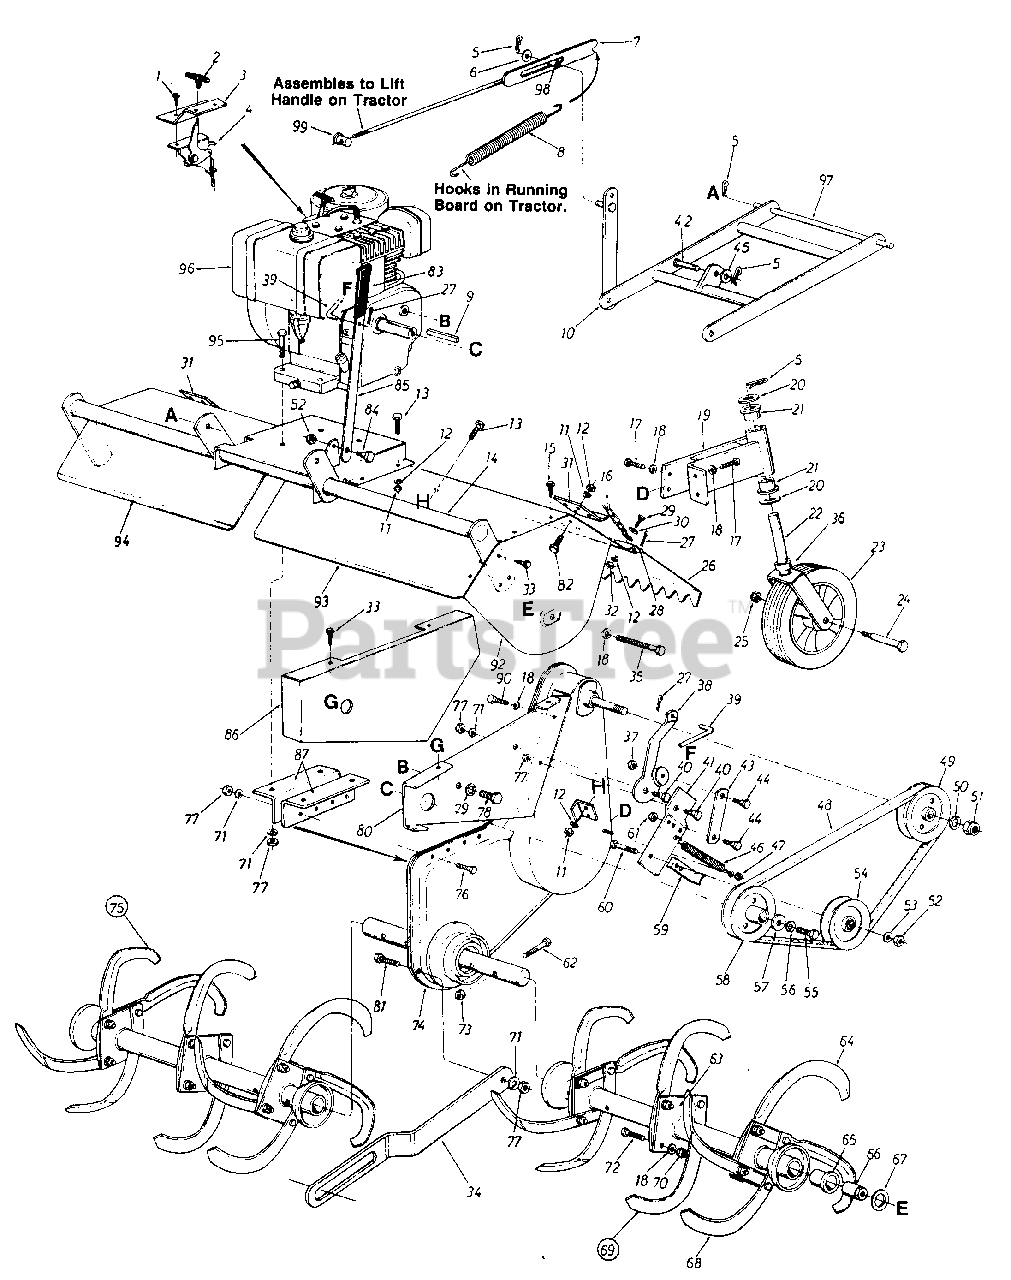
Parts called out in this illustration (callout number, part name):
1	Hex Wash. Hd. Self-Tap Scr. #8 x .50" Lg.
2	Throttle Control Knob
3	Throttle Control Bracket
4	Throttle Control Ass'y. Comp.
5	Internal Cotter Pin
6	Fl-Wash. 1/2" I.D. x .93" O.D.
9	Sq. Key 1/4" x 1/4" x 2.00" Lg.
12	L-Wash 1/4 " I . D
13	Hex Bolt 1/4-28 X .62" Lg.
16	#2 Dog Chain x 20" Lg.
17	Hex Wash. Hd. Self-Tap Scr. 3/8-24 x .75" Lg.
18	L-Wash. 3/8" I.D.
21	Flange Bearing 3/4" I.D. x 1.00" O.D.
24	Shoulder Bolt .623" I.D. x 3.62" Lg.
25	Hex Cent. L-Nut 7/16-14 Thd.
28	L.H. Flap Rod
29	Hex Bolt 1/4-20 x .6Z" Lg.
30	Fl-Wash. 1/4" I.D.
33	Hex Wash. Hd. Self-Tap Scr. 1/4" x.62" Lg.
36	Spacer .752" I.D. x 1.25" O.D.
37	Hex Cent. L-Nut 5/16-18 Thd.
40	Shoulder Bolt 7/16" Dia. x 1.75" Lg.
45	Fl-Wash. .50" I.D. x 1.0" O.D. x .06
46	Extension Spring .62" O.D. x 6.12" Lg.
47	Hex Crown Nut 3/8-24 Thd.
48	"V"-Belt '/2" x 43" Lg. (Kevlar)
49	1/2" "V"-Pulley 4.75" O.D. x .625" Bore
50	L-Wash. 5/8" I.D.
51	Hex Ins. L-Nut 5/8-18 Thd.
52	Hex Cent. L-Nut 3/8-16 Thd.
53	Fl-Wash. 3/8" I.D.
54	Idler Pulley 4.0" O.D.
55	Hex Bolt
56	L-Wash. 7/16" I.D.
57	Fl-Wash. 7/16" I.D. x 1.38"
58	'/2" "V'-Pulley .475" O.D. x 1.00" Bore
61	Hex Cent. L-Nut 5/16-18 Thd.
62	Hex Bolt 7/16-14 x 2.00" Lg.
66	Spacer
67	Thrust Wash. '/2" I.D. x 1.55"
71	L-Wash. 5/16" I.D.
72	Hex Bolt 3/8-24 x 1.5" Lg.
73	Hex Cent. L-Nut 7/16-14 Thd.
77	Hex Nut 5/16-18 Thd.
78	Hex Bolt '/2-20 x .88" Lg. (Grade 5)
79	L-Wash. '/2" I.D.
80	Clutch Support Bracket
81	Shld. Bolt .435 Dia. x .265 5/16-18 Thd.
82	Hex Bolt 1/4-28 x .75" Lg.
83	Plastic Grip
84	Shoulder Bolt .498 Dia. x .212 Lg.
96	8 H.P. Engine
97	Hitch Rod
98	Push Bar Sleeve .503" I.D. x .624" O.D.
99	Ferrule
04975-0637	PLATE ASSY-SIDE-LH - POWDER BLACK (0637)
04978-0637	SUPPORT-SWIVEL WHE - POWDER BLACK (0637)
04983-0637	L.H.-Tine Shield - POWDER BLACK (0637)
14298-0637	SHROUD-CLUTCH SUP - POWDER BLACK (0637)
